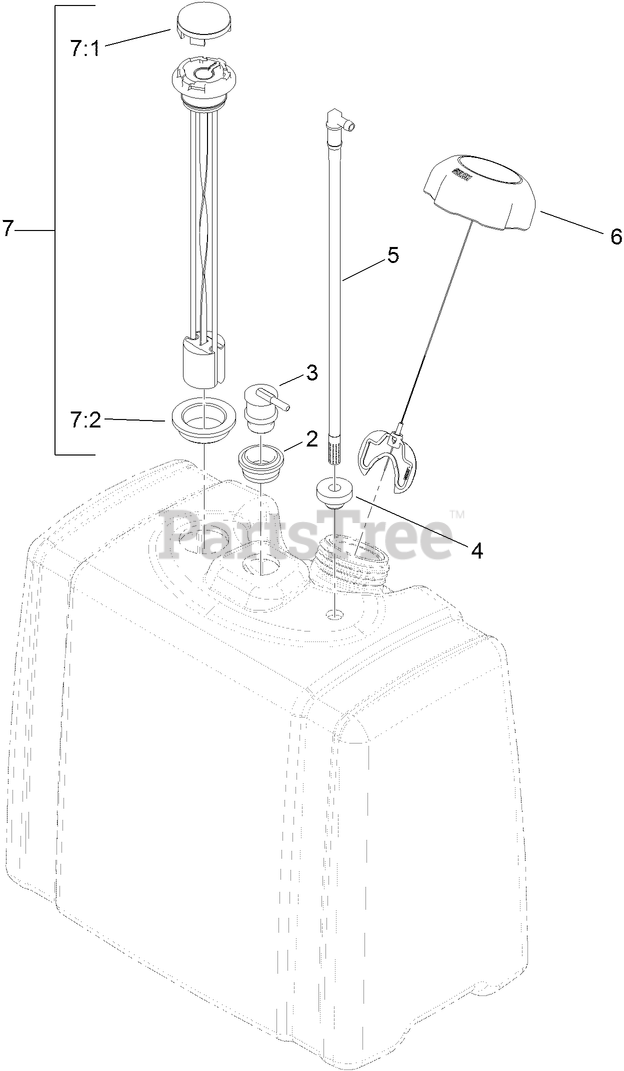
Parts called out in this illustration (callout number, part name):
2	GROMMET
3	VALVE-ROLLOVER
4	BUSHING
5	PIPE-STAND
6	CAP-FUEL
7	GAUGE ASM
7:1	DIAL-GAUGE
